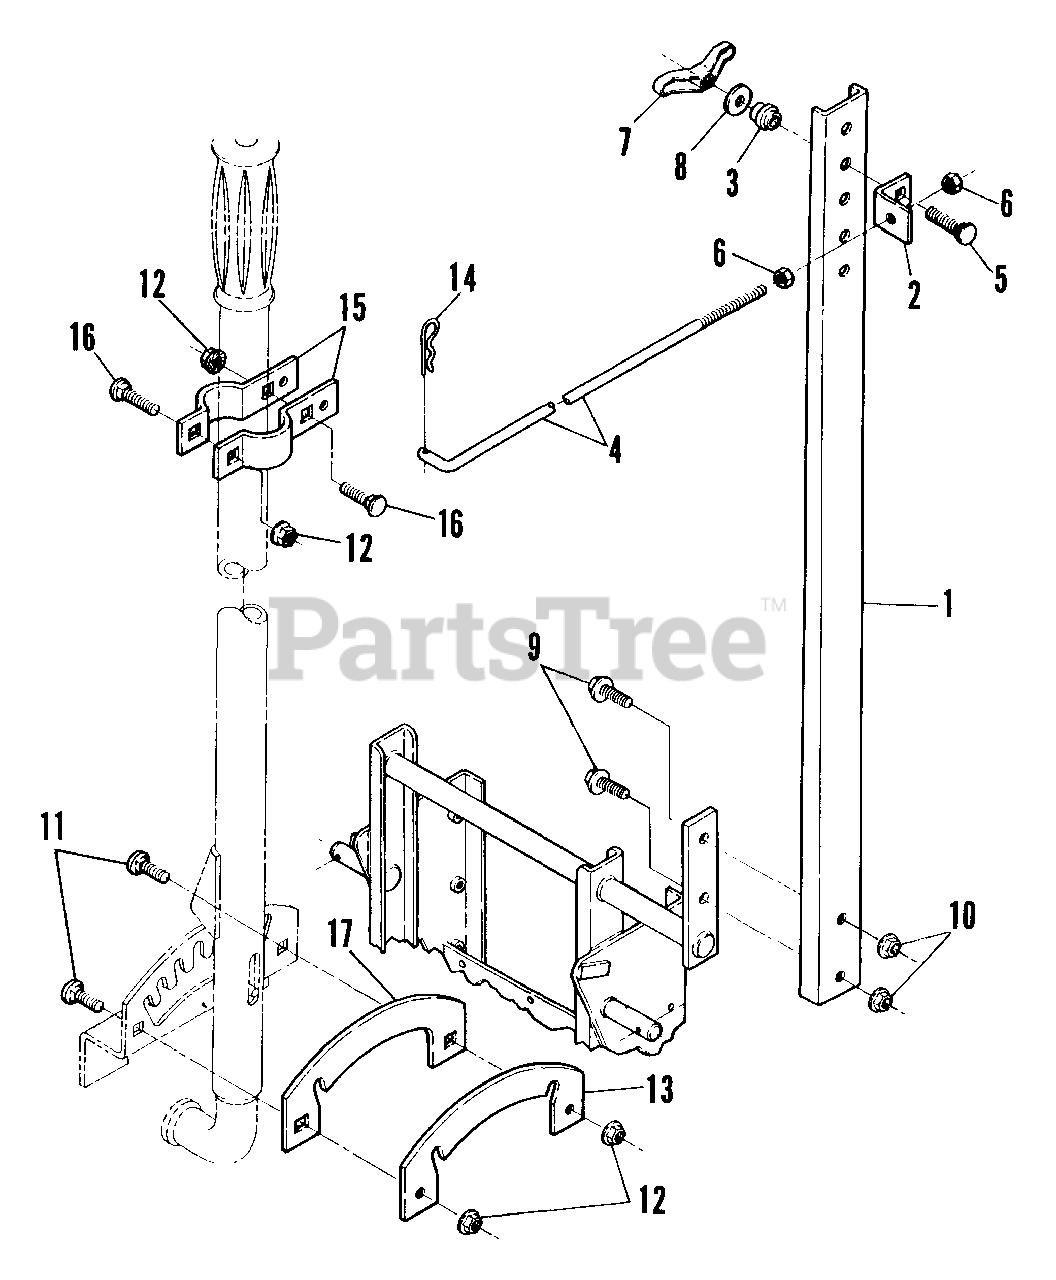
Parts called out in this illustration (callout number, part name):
1	ARM, Lift
2	SWIVEL, Lift Rod
3	SPACER
4	ROD, Lift
5	BOLT, 5/16 - 18 x 1-3/8" Carriage
6	NUT, 3/8 - 16 Hex
7	NUT, 5/16 - 18 Wing
8	WASHER, 5/16" x 1-1/4" x 3/32" Flat
9	SCREW, 1/2 - 13 x 1" Hex Head Cap Flange Lock
10	NUT, 1/2 - 13 Hex Flange Lock
11	BOLT, 1/4 - 20 x 5/8" Flat Head Carriage
12	NUT, 1/4 - 20 Hex Flange Lock
13	PLATE, Quadrant
14	HAIR PIN
15	TAB
16	BOLT, 1/4 - 20 x 1/2" Short Neck Carriage
17	PLATE, Quadrant Float
